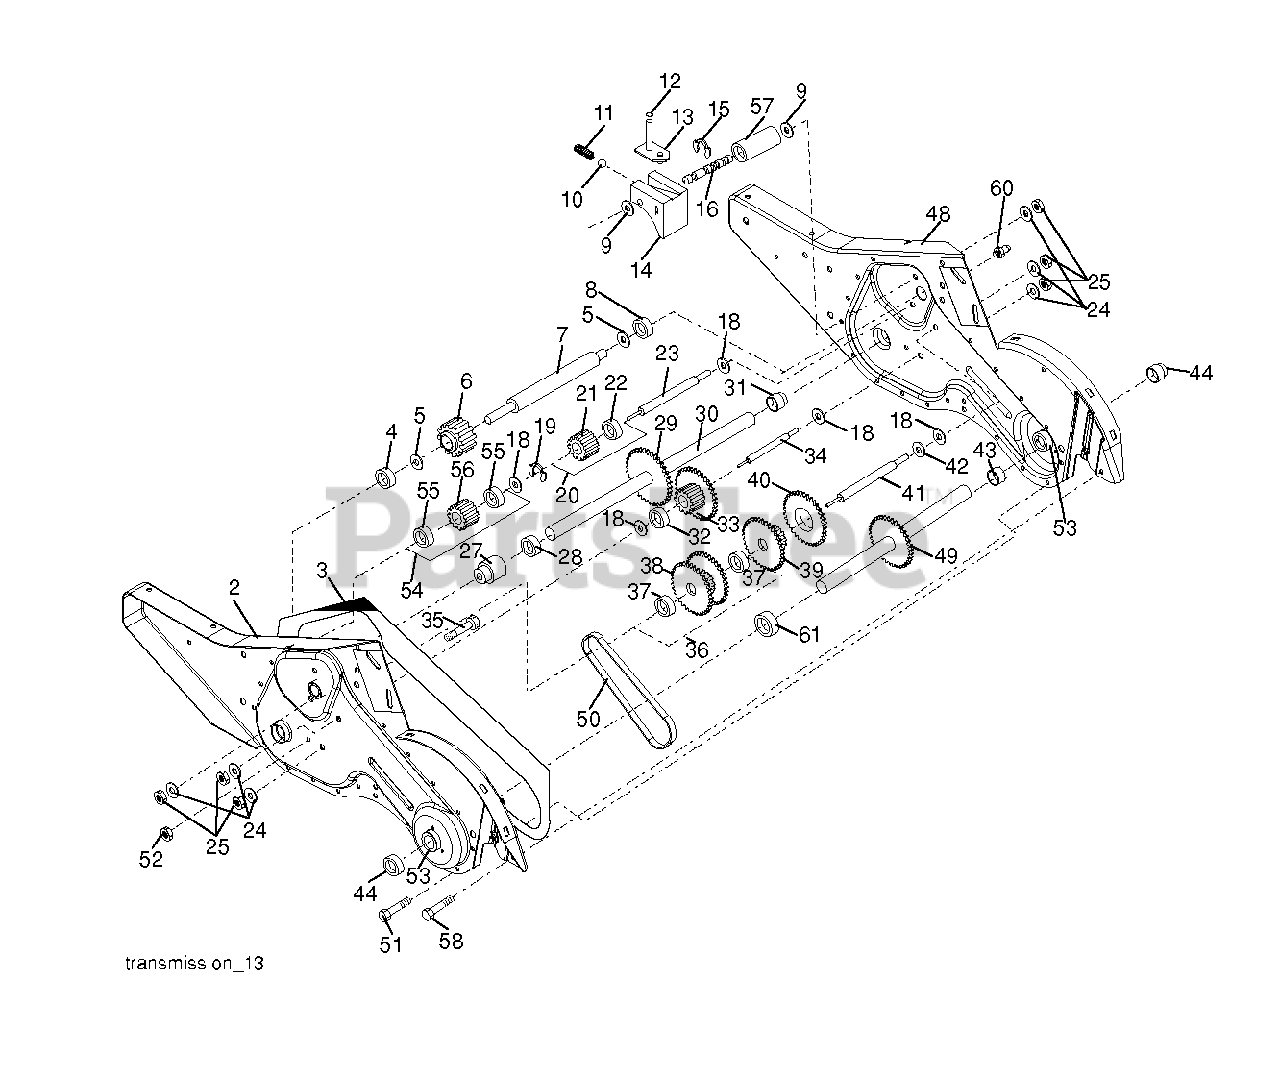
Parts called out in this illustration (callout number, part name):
1	TRANSMISSION.ASM.17
2	GEARCASE.ASM.DRT.LH.
3	GASKET.GEARCASE.CRT/DRT.TILLER
4	NEEDLE BRNG LT
5	THRUST WASHER
6	GEAR.PINION.INPUT.DRT
7	SHAFT.INPUT.D.9TEETH
9	WASHER, SEAL (2 2)
10	BALL, STEEL
11	SPRING-SHIFT CRT
13	BRACKET ASM.SHIFT.CRT
14	SHIFT FORK TI
16	SHAFT.SHIFT.DRT
20	GEAR ASSY CRT
21	GEAR-REV IDLR CRT
22	NEEDLE BEARING TI
23	SHAFT.IDLER.REVERSE.CRT
24	LOCKWASHER
25	NUT.ASF.HEX.7/16
27	BEARING, SHAFT, GROUNDDRIVE LH
30	GROUND SHAFT ASS'Y
31	BEARING, SHAFT RH CRT
33	SPRCKT 8 GEAR CRT
34	SHAFT.SECONDARY.REDUCTION.CRT
35	SCRW WHIZ LOK CRT
36	GEAR & SPROCKET.ASM.WBEARIN
37	BEARING.NEEDLE.CRT
38	ASM.GEAR & SPROCKET
39	GEAR.CLUSTER.DRT.TILLER
41	SHAFT.REDUCTION.FIRST.DRT
42	BRNG RACE T
44	SEAL ASM, OIL
48	GEARCASE.ASM.DRT.RH.
49	SHAFT.ASM.TINE
50	CHAIN.TILLER
51	SCREW
53	BEARING KIT
54	GEAR.ASM.DRT.TILLER
55	BEARING.NEEDLE
56	GEAR.DRT.IDLER
57	SPACER.SPLIT
58	BOLT SHOULDER 1/4-20 UNC X.875
60	FITTING.GREASE.TAPERED
61	SPACER.1.015X1.50X.650
